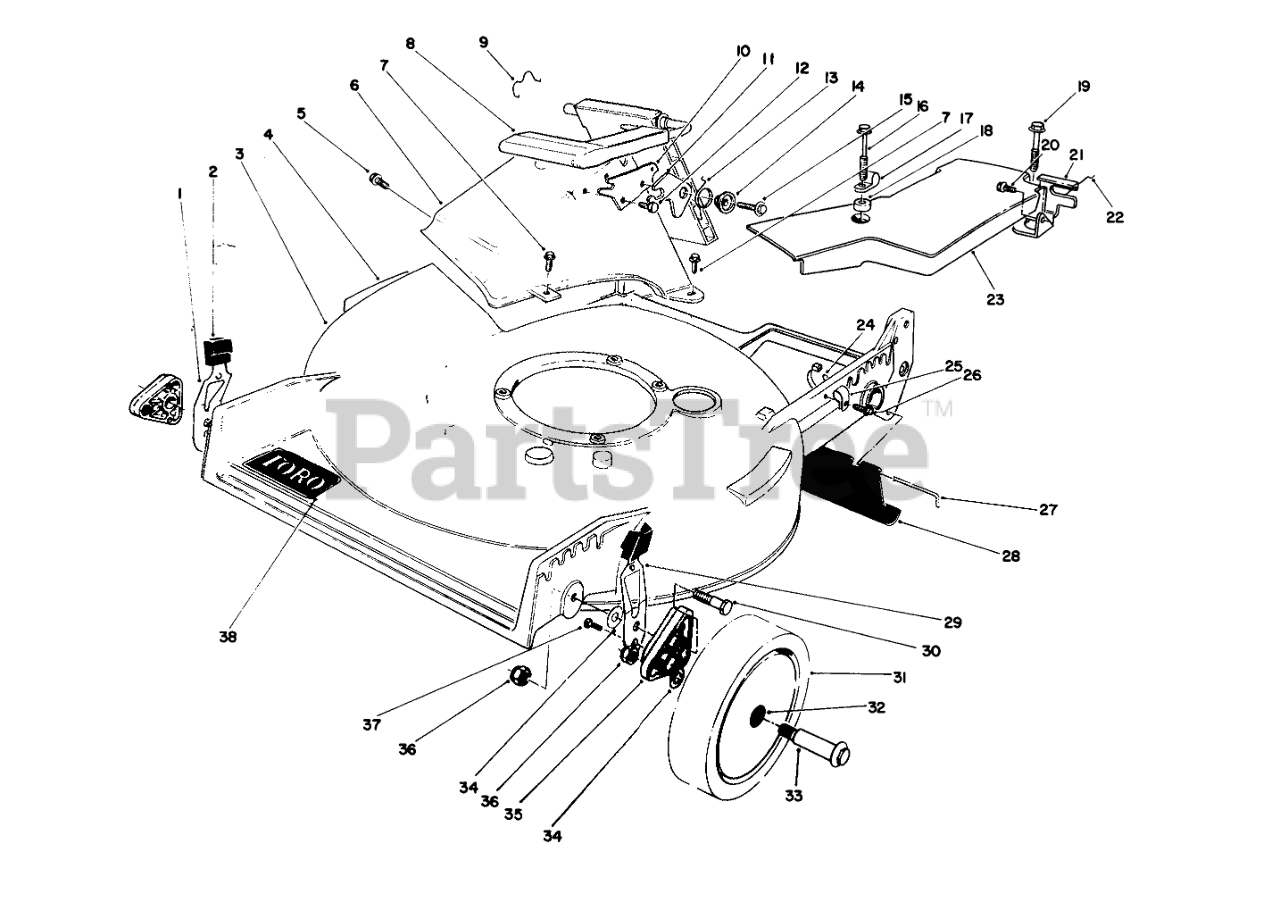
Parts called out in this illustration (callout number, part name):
1	RH SPRING ARM ASSEMBLY
2	KNOB-ARM
3	Housing (Incl. Ref. #4 & 38)
4	DECAL-DANGER
5	SCREW AND WASHER ASM
6	Tunnel-Discharge
7	SCREW-HWH
8	Discharge Door Assembly
9	DOOR RET SPRING
10	DOOR LATCH PLATE
11	SAFETY LATCH
12	SCREW-PLASTITE
13	TORSION SPRING
14	DOOR SPACER
15	SCREW-HWH
16	SCREW-SPECIAL
17	CLAMP-CABLE
18	WASHER
19	SCREW-HHFTF
20	SCREW-HWHTF
21	Bracket-Traction Adj.
22	RETAINER-CABLE
23	Cover-Belt
24	TIE-CABLE
25	CLAMP-CABLE
26	SCREW
27	ROD-SHIELD
28	SHIELD-TRAILING
29	LH SPRING ARM ASSEMBLY
30	SCREW-SHOULDER
31	Wheel & Tire Assembly (Incl. Ref. #32)
32	BUSHING
33	WHEEL BOLT
34	WASHER
35	ARM-PIVOT, FRONT
36	Nut
37	SCREW-HWH
38	DECAL
